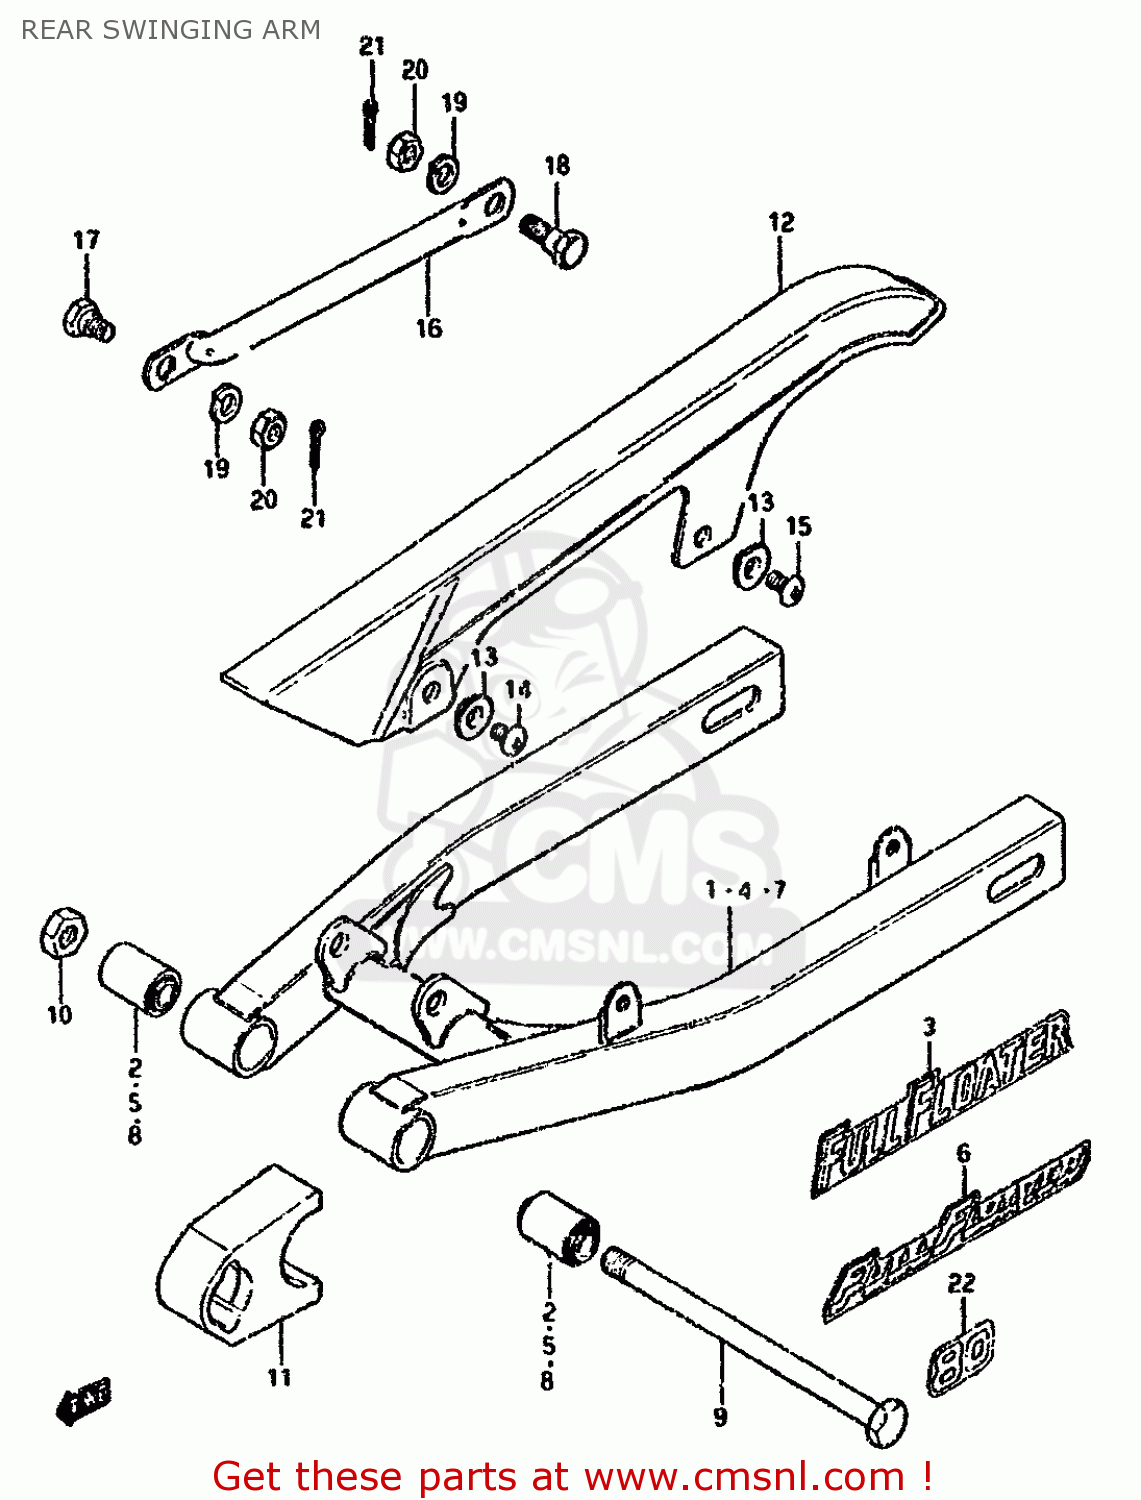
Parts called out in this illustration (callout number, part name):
1	SWING ARM ASSEMBLY,REAR
2	BUSH
3	EMBLEM
4	SWING ARM ASSEMBLY,REAR
5	BUSH
6	EMBLEM,SWING ARM
7	SWINGINGARM ASSY,RR
8	BUSH
9	SHAFT,RR SWINGINGARM PIVOT
10	NUT
11	BUFFER,CHAIN TOUCH DEFENSE
12	CASE,CHAIN
13	WASHER
14	SCREW
15	SCREW
16	TORQUELINK,RR
17	BOLT(8X22)
18	BOLT(8X26.5)
19	LOCK WASHER
20	NUT
21	PIN 20X20
22	EMBLEM,SWING ARM
